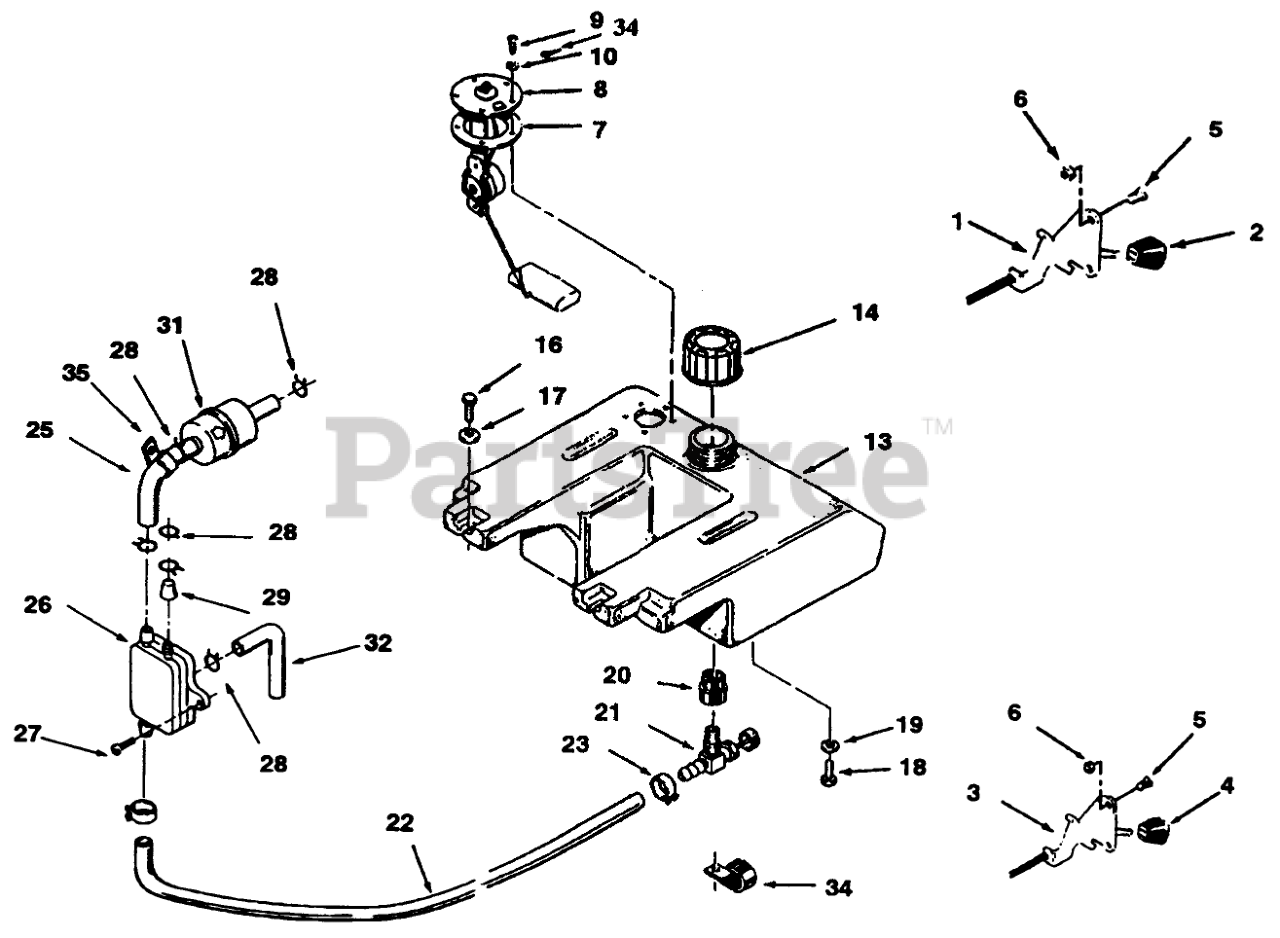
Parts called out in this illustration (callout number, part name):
1	CONTROL-THROTTLE
2	KNOB-CONTROL
3	CONTROL-CHOKE
4	KNOB-CONTROL
5	Screw
6	Nut
7	GASKET-SENDER, FUEL
8	SENDER-FUEL LEVEL
9	Screw
10	WASHER-LOCK
13	Tank-Fuel (Includes Items 20 & 21)
14	GAS CAP ASM
17	WASHER-FLAT
18	SCREW-HH
19	WASHER-LOCK
20	BUSHING
21	VALVE-FUEL
22	FUEL HOSE 75" OF 6554
23	Clamp
24	Clamp
25	Hose
26	Fuel Pump
27	SCREW-TAPPING PAN HD
28	CLAMP-HOSE
29	Cap
30	Clamp
31	Filter-Fuel
32	Hose
34	TERMINAL-GROUND
35	Clip
